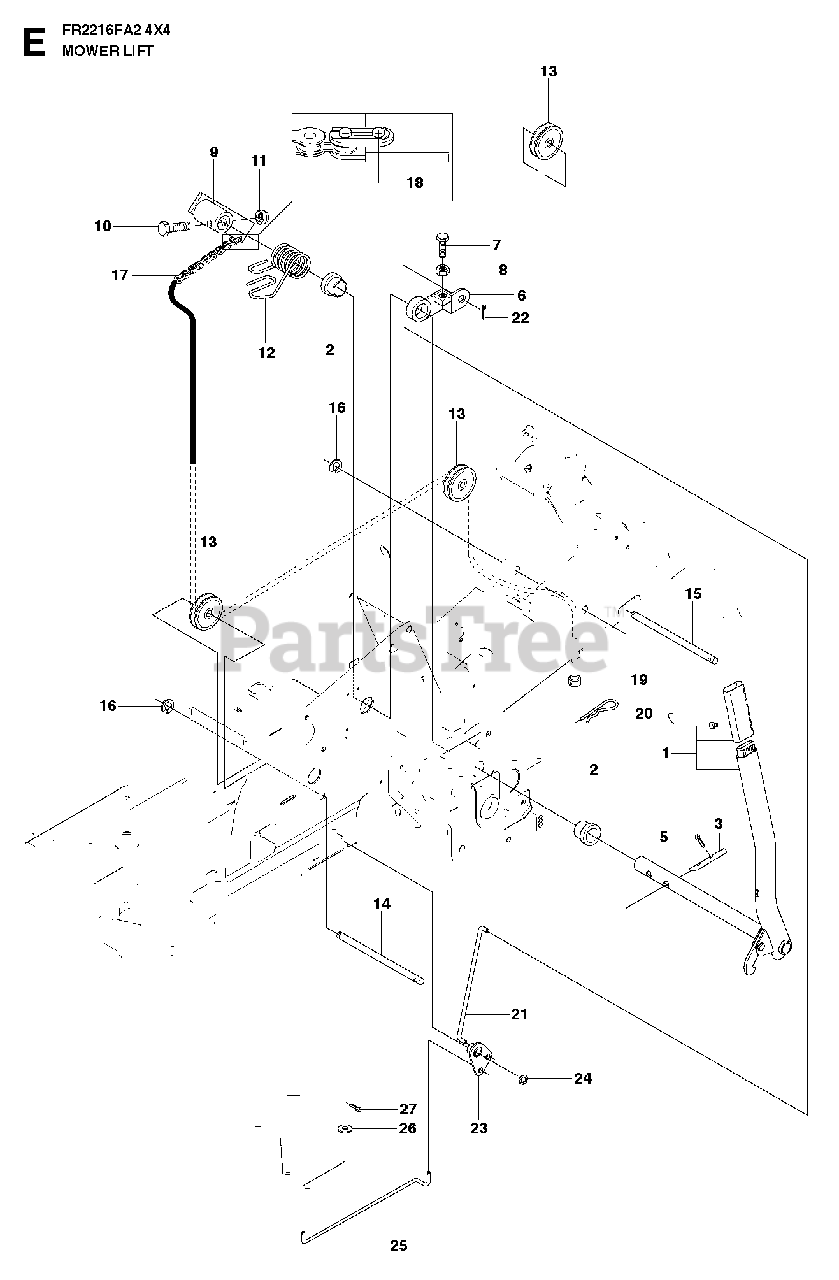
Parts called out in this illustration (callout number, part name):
1	LIFTING LEVER ASSY
2	BUSH
5	SPLIT PIN
6	LEVER CLUTCH
9	LIFTING ARM
16	LOCK RING
21	CONNECTION ROD
22	SPLIT PIN
24	RETAINING RING
25	CONNECTION ROD
27	SPLIT PIN
